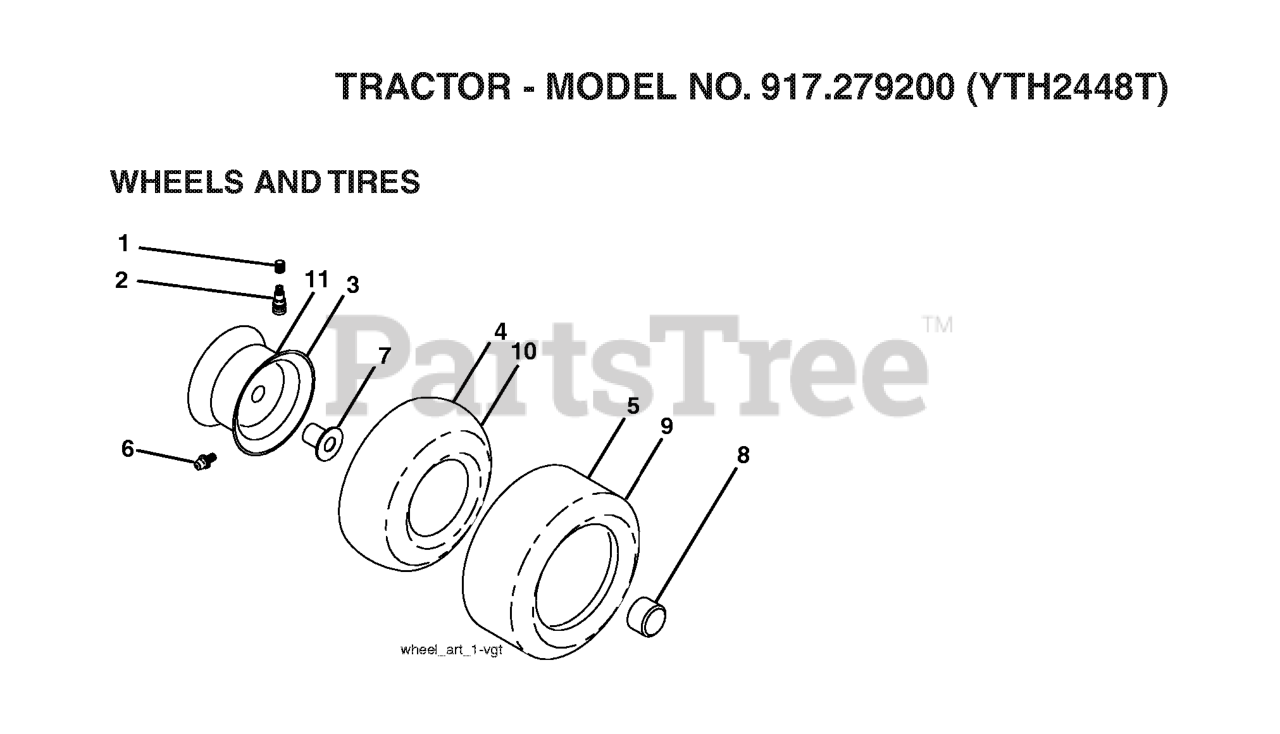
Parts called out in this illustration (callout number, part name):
2	VALVE STEM LT
3	RIM ASM 6" FRONT SILVER
4	TUBE.16X6.5/7.5-8
5	TIRE HEAVY DUTY
6	FITTING LT.
7	BEARING.FLANGE
8	CAP, AXLE BLK
9	TIRE.20X8-8.TURF.SAVER
10	TUBE.23X9.5-12
11	RIM ASM 8" REAR SILVER
